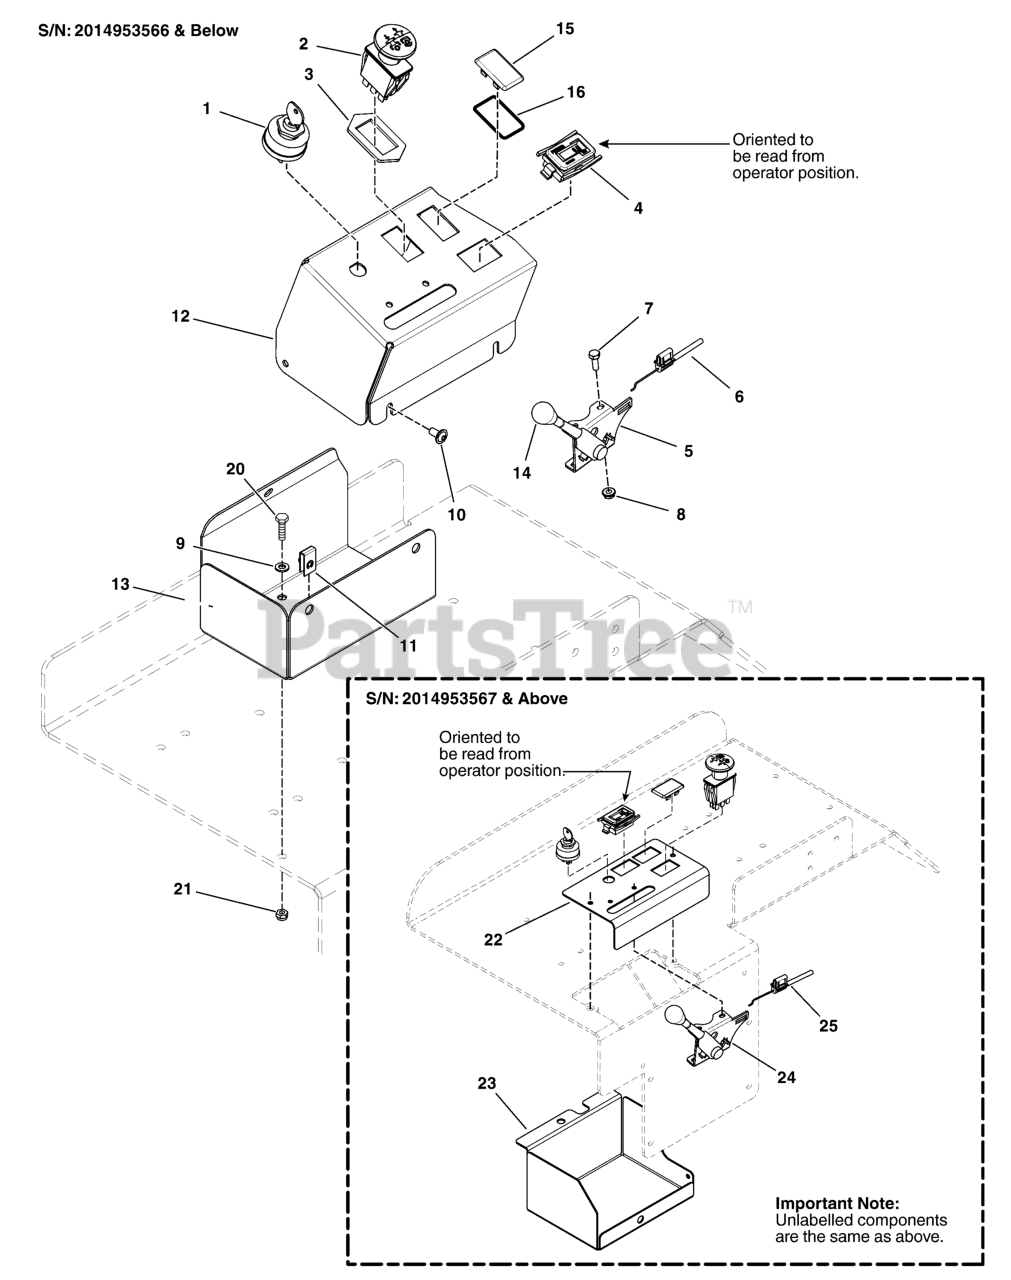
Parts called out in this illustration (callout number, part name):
1	SWITCH, IGNITION, 6 POST
2	SWITCH, BLADE ENGAGEMENT
3	RING, SWITCH RETAINER
4	HOUR METER, W/ SUPRESSOR
5	LEVER, THROTTLE CONTROL, HEAVY-DUTY
6	CABLE, THROTTLE, 52"
7	SCREW, #10-24 X 3/4" ROUND PHILLIPS
8	NUT, Hex, Nylon Lock, #10-24
9	WASHER, 5/16" SAE
10	SCREW, ALLEN HEAD 1/4-20X.500 ZINC PHOS
11	BODY CLIP, 1/4-20 X 1/2" DEEP
12	CONTROL PANEL, TOP - BLK
13	CONTROL PANEL, BOTTOM - BLK
14	THROTTLE CONTROL HANDLE/KNOB
15	PLUG, .820X1.44 HOLE, BLACK PLASTIC
16	O-RING, 7/8" ID X 1/16" W
20	BOLT, 5/16-18 X 3/4 GD5
21	NUT, 5/16-18 HEX NYLOCK FLANGE NUT
22	PLATE, INSTRUMENT CONTROL PANEL
23	PLATE, INSTRUMENT CTRL SHIELD, PROPANE - BLK
24	HANDLE, THROTTLE CONTROL
25	CABLE, THROTTLE 47"
